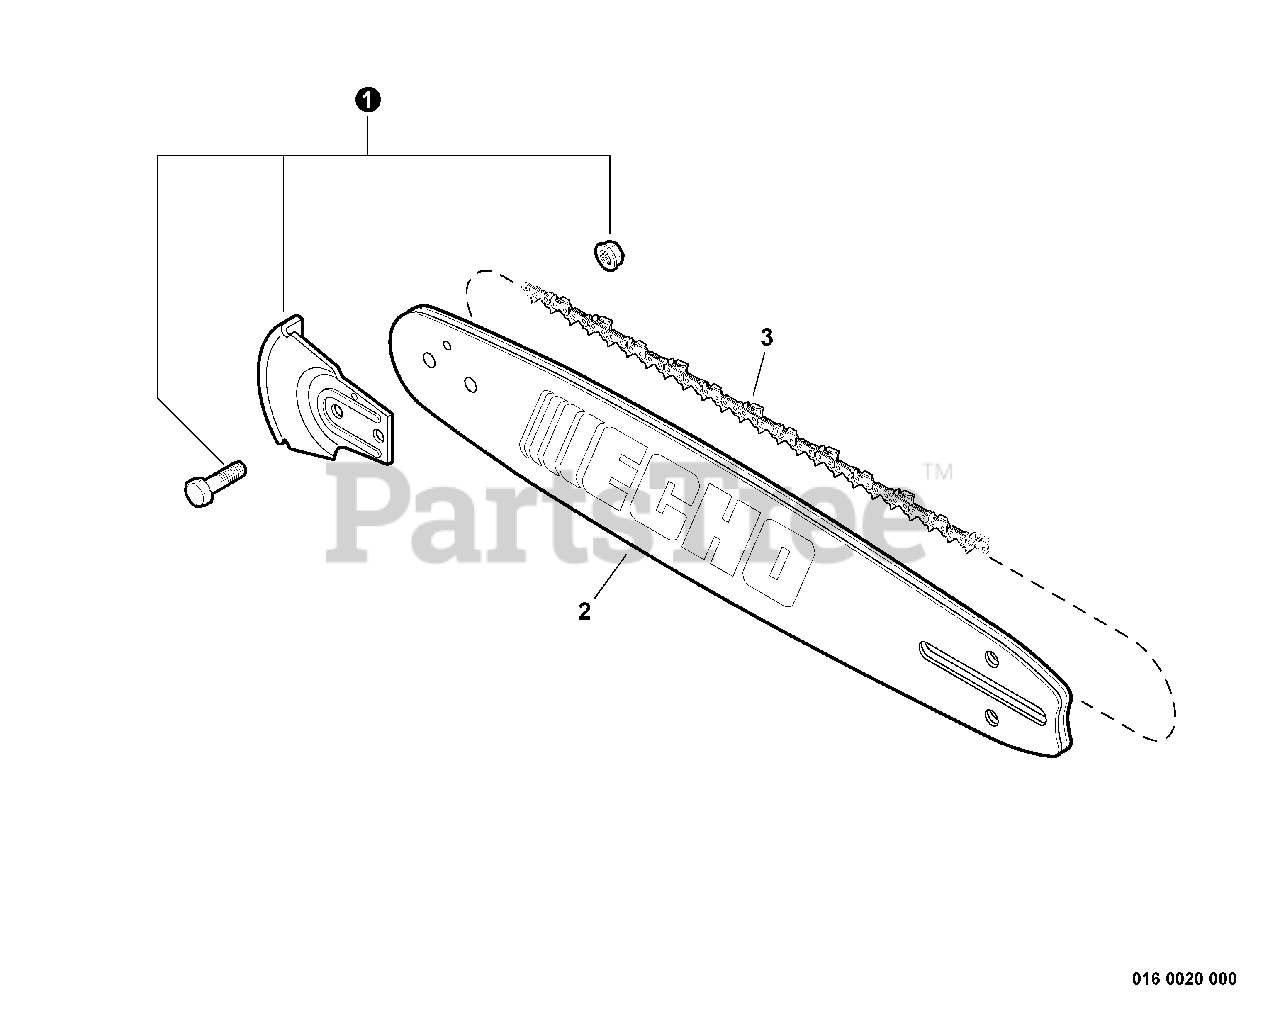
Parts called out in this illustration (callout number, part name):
1	KICK GUARD KIT
2	GUIDE BAR, 20" PRO-LITE 0.325
3	SAW CHAIN 20"
